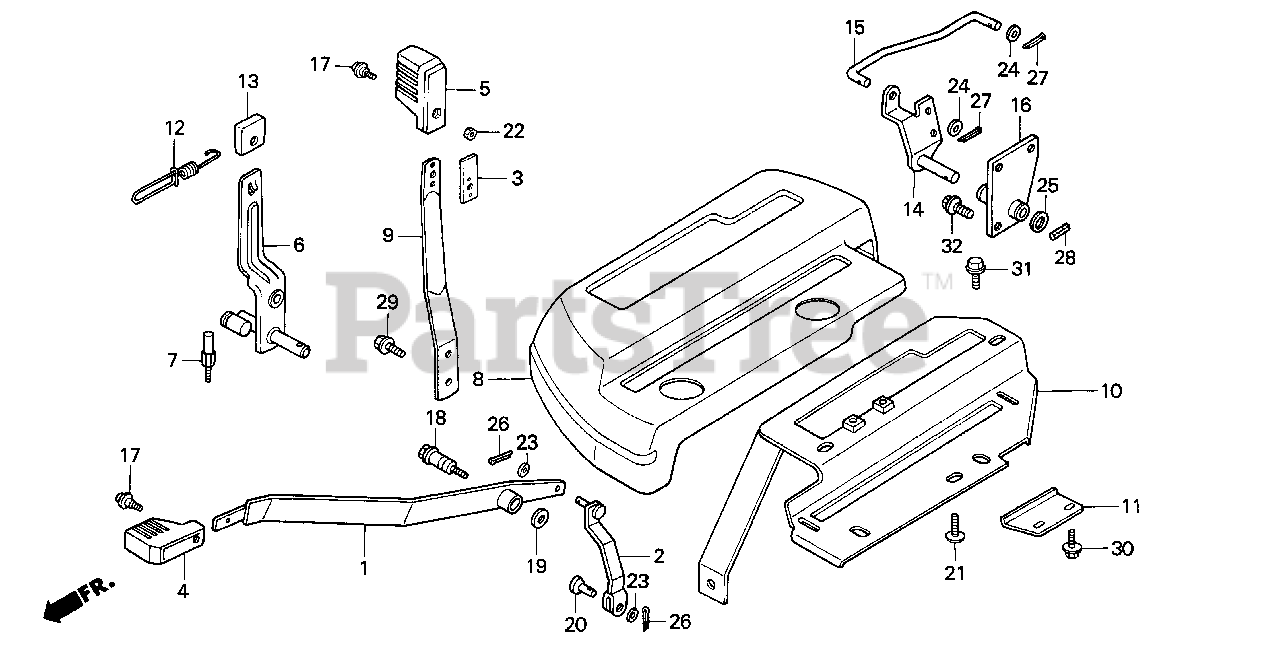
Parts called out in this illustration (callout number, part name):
3	PLATE, P.T.O. SHIFT LEVER
5	KNOB, CHANGE LEVER
8	PANEL, R. CONTROL *R136* (DIANA RED)
9	LEVER, HYDRAULIC CONTROL
10	GUIDE, HYDRAULIC CONTROL LEVER
11	PLATE, TWO MOTION
12	SPRING, CONTROL LEVER RETURN
14	SHAFT, HYDRAULIC CONTROL
15	JOINT, HYDRAULIC CONTROL
16	BASE, HYDRAULIC CONTROL
17	SCREW, HINGE PATCH
21	SCREW, TAPPING (6X12)
22	NUT, HEX. (5MM)
24	WASHER, PLAIN (8MM)
25	WASHER, PLAIN (12MM)
27	PIN, SPLIT (2.5X30)
28	PIN, SPRING (4X20)
29	BOLT, FLANGE (6X10)
30	BOLT, FLANGE (6X12)
31	BOLT, FLANGE (8X12)
32	BOLT, FLANGE (8X14)
